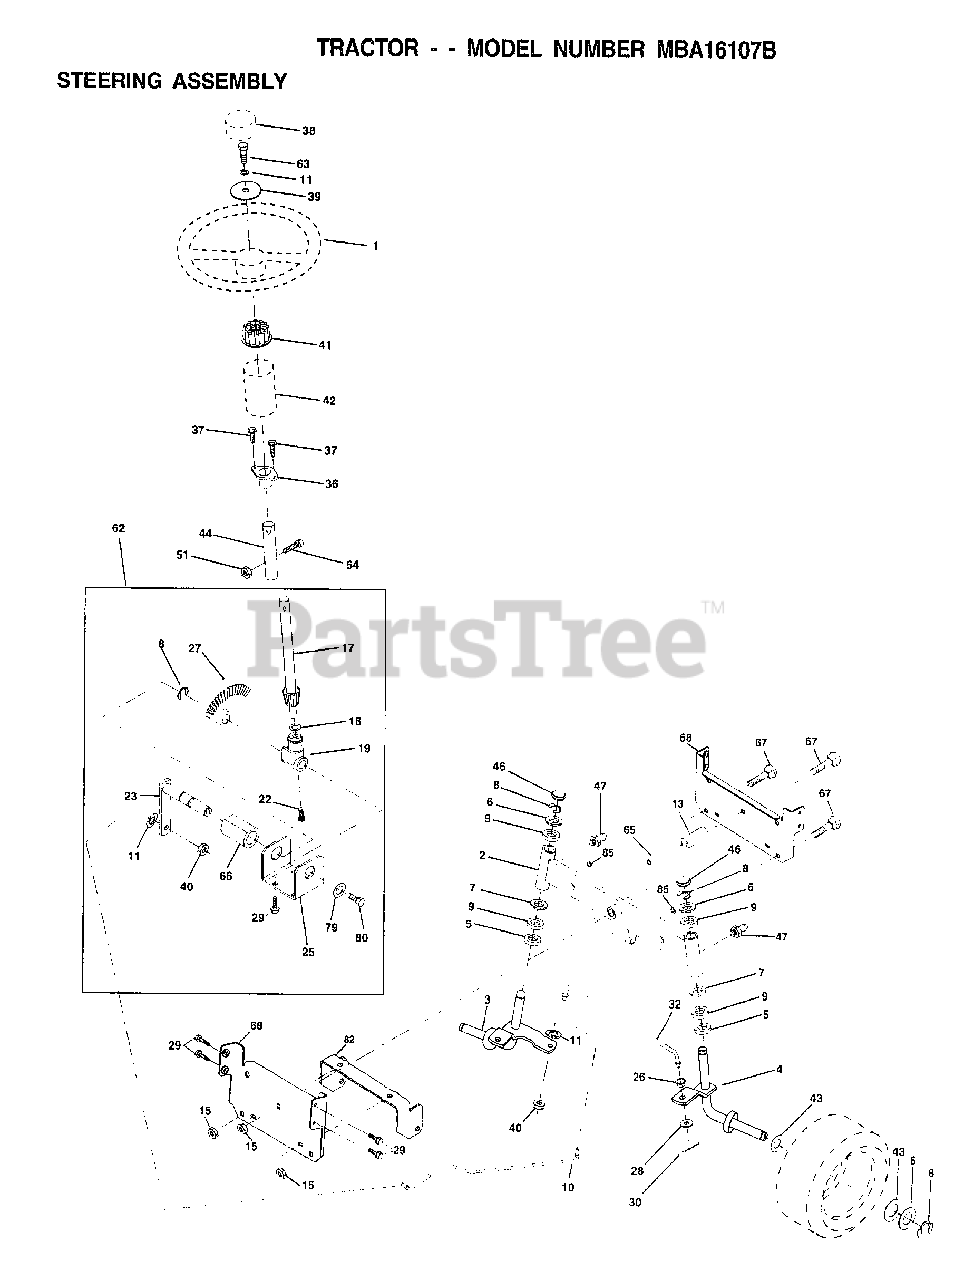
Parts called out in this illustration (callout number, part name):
2	AXLE ASM
3	SPINDLE ASM
4	SPINDLE ASM
5	WASHER .T
6	WASHER
7	WASHER
8	RING
9	COL. SRTG. BEAR.
10	LINK DRAG
11	LOCKWASHER
13	SPACER BEARING
15	NUT.HXFLG.LOCK.
17	SHAFT ASM STEERIN
18	THRUST WASHER
19	SUPPORT.SHAFT.STEER
22	SCREW.HX.WSH.HD
23	SHAFT.ASM.PITMAN
25	BRKT-STEERING
26	BUSHING.DRAGLINK
27	GEAR SECTOR
28	WASHER
29	SCREW
30	COTTER PIN
32	TIE ROD
36	BUSHING.STEERING
37	"SCREW-TT,10-32 FL"
38	CAP WHEEL STEER
39	WASHER
40	GRIPCO NUT
41	ADAPTER LT
42	BOOT.STEERING.DASH.P/L
43	WASHER
44	EXT SHAFT STEERIN
46	CAP
47	ZERK M
51	NUT
54	BOLT
62	KIT.STEER.ASM
63	BOLT
65	"SPACER BRCAE,AXLE"
66	"BEARING-ARM,PITMA"
67	BOLT RDHD 3/8-16
68	BRACE AXLE
79	WASHER
80	BOLT.HX.NYLON3/8-16X3/
82	BRKT SUSP CHASSIS FRT
85	XMAS TREE FASTNER
